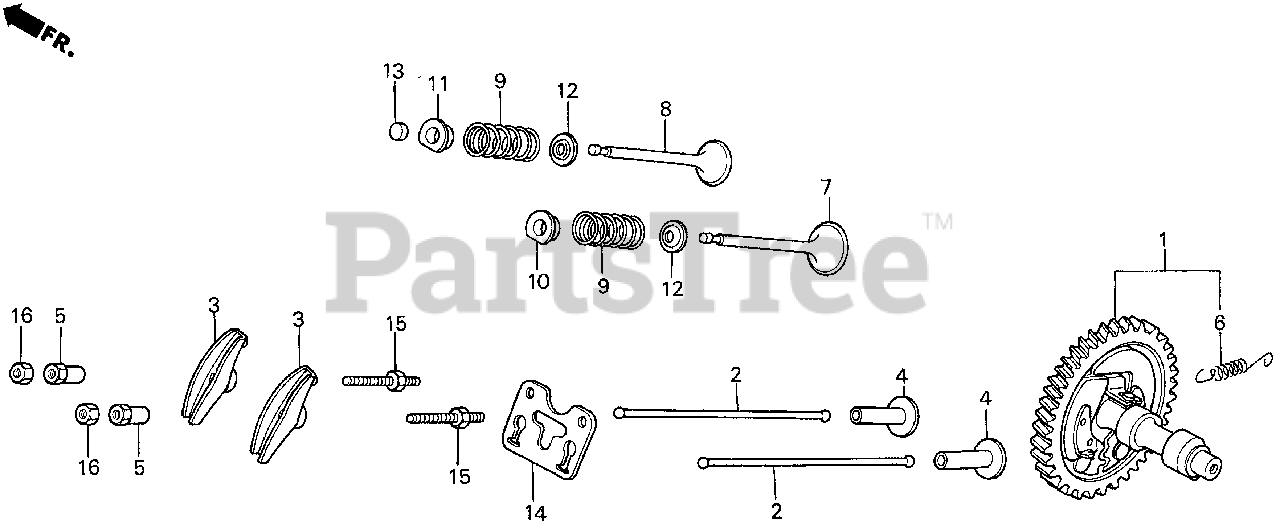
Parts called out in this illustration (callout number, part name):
1	CAMSHAFT ASSY.
1	CAMSHAFT
2	ROD, PUSH
3	ARM, VALVE ROCKER
4	LIFTER, VALVE
5	PIVOT, ROCKER ARM
6	SPRING, WEIGHT RETURN
7	VALVE, IN.
8	VALVE, EX.
9	SPRING, VALVE
10	RETAINER, IN. VALVE SPRING
11	RETAINER, EX. VALVE SPRING
12	SEAT, VALVE SPRING
13	ROTATOR, VALVE
14	PLATE, PUSH ROD GUIDE
15	BOLT, PIVOT (8MM)
16	NUT, PIVOT ADJUSTING
